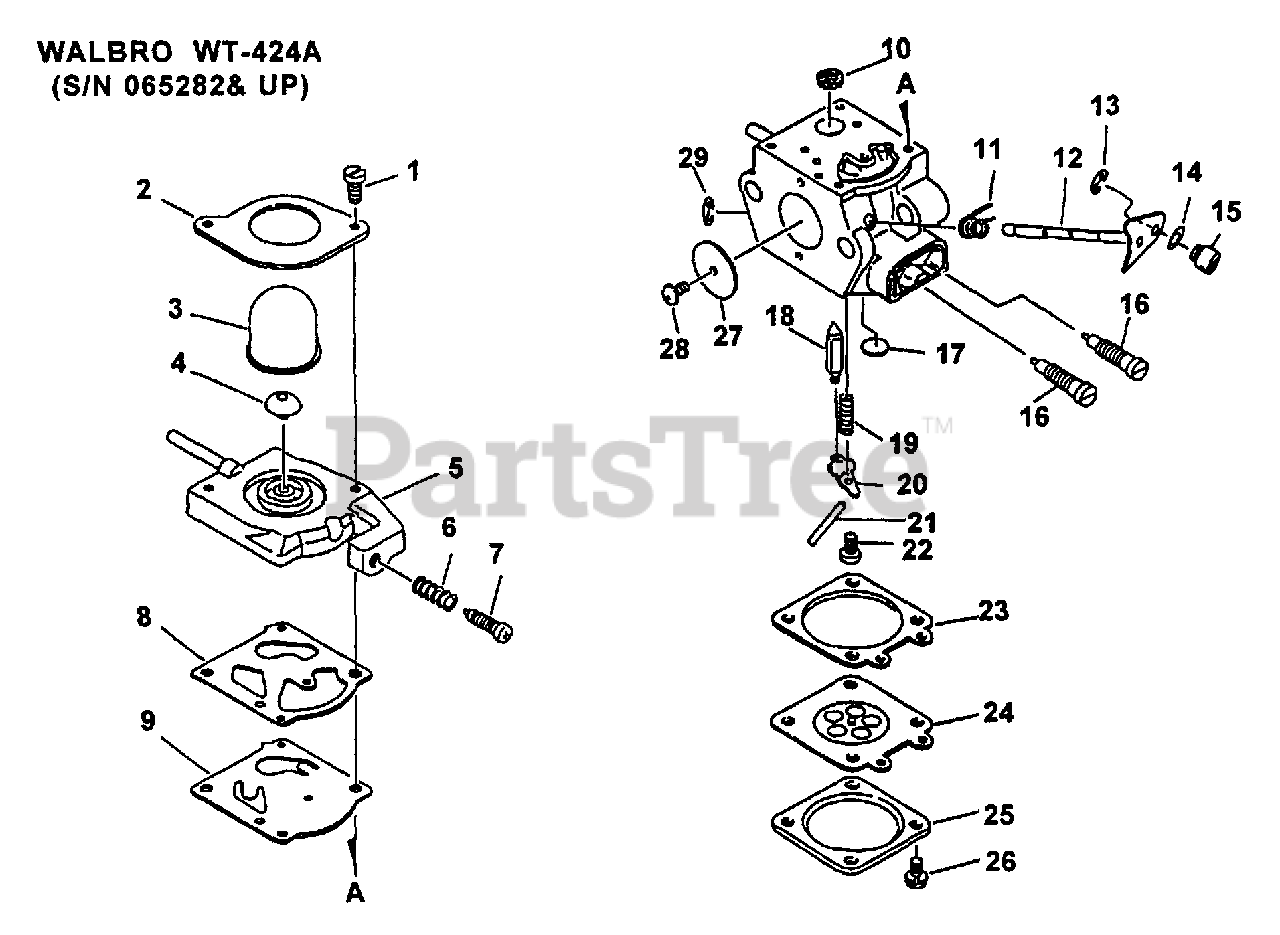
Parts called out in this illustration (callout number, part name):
1	SCREW, PUMP COVER
2	RETAINER, PURGE BULB
3	BULB, PURGE
4	VALVE, CHECK
5	BASE, PURGE
6	SPRING, IDLE ADJUST
7	SCREW, IDLE ADJUST
8	GASKET, PURGE
9	DIAPHRAGM, PURGE
10	REPAIR KIT
11	SPRING, THROTTLE RETURN
12	SHAFT, THROTTLE
13	RING, RETAINING
16	NEEDLE - MIXTURE
17	PLUG, WELCH
18	VALVE, INLET NEEDLE
19	SPRING, METERING LEVER
20	LEVER, METERING
21	PIN, METERING LEVER
22	SCREW, METERING LEVER PIN
23	GASKET, METERING
24	DIAPHRAGM, METERING
25	COVER, METERING
26	SCREW
27	VALVE, THROTTLE
29	RING, RETAINING
